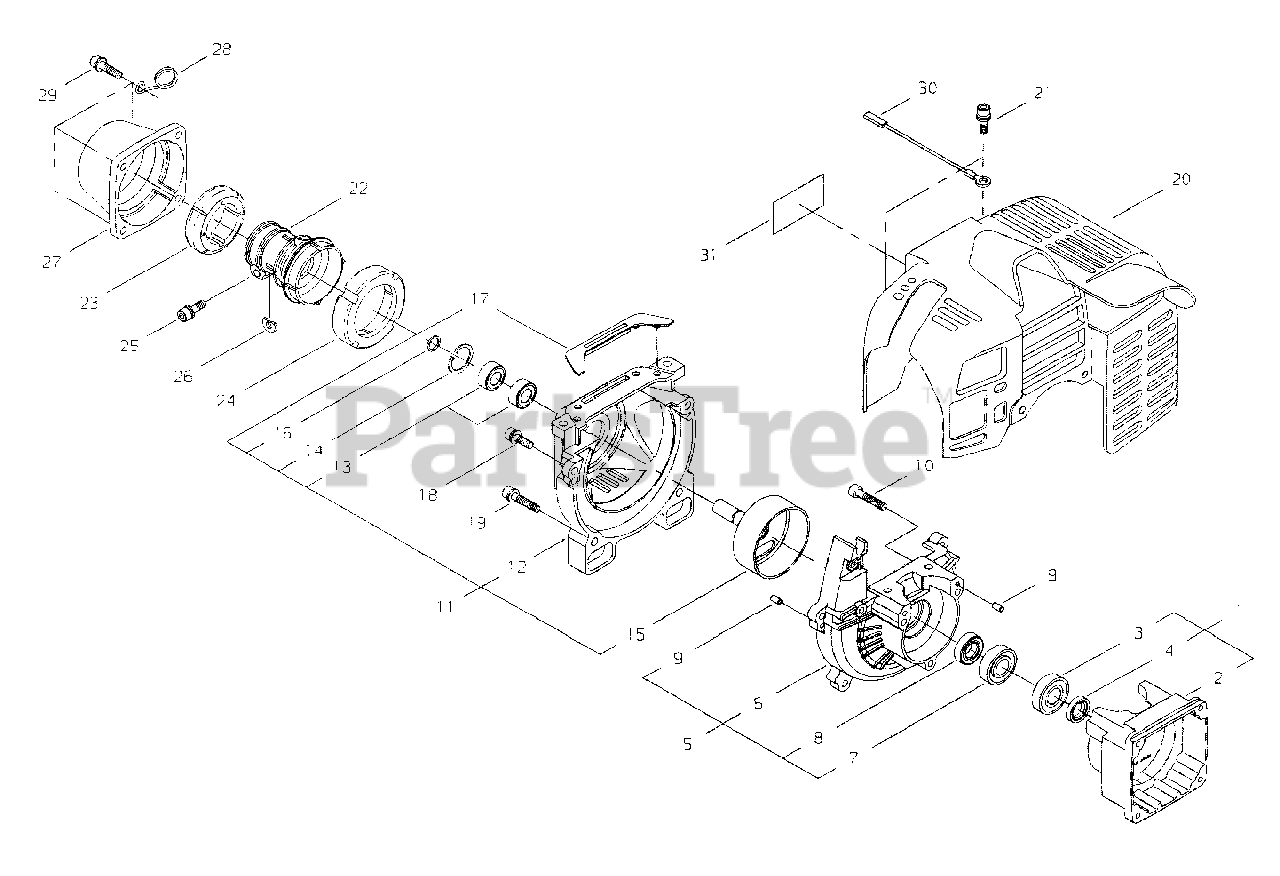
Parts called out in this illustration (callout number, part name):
1	CRANKCASE ASSY, S
2	CRANKCASE S
3	BEARING, BALL 6001 C3
4	SEAL, OIL 12
5	CRANKCASE ASSY, M
6	CRANKCASE M
7	BEARING, BALL 6001 C3
8	SEAL, OIL 12
9	PIN, LOCATING Ø4×8
10	BOLT 5×25
11	COVER, FAN
12	COVER, FAN (RED)
13	BEARING, BALL 6000DDU
14	RING, SNAP Ø26
15	DRUM, CLUTCH
16	RING, SNAP WR10
17	CUSHION
18	BOLT M5×16
19	BOLT M5×30
20	COVER, ENGINE - RED
21	BOLT M5×16
22	CUSHION, AV
23	CUSHION, FRONT
24	HOLDER, REAR CUSHION
25	BOLT M5×25
26	D-WASHER
27	COVER, AV CUSHION (RED)
28	HOLDER, THROTTLE CABLE
29	BOLT M5×20
30	LEAD - GROUND
31	LABEL, MODEL
